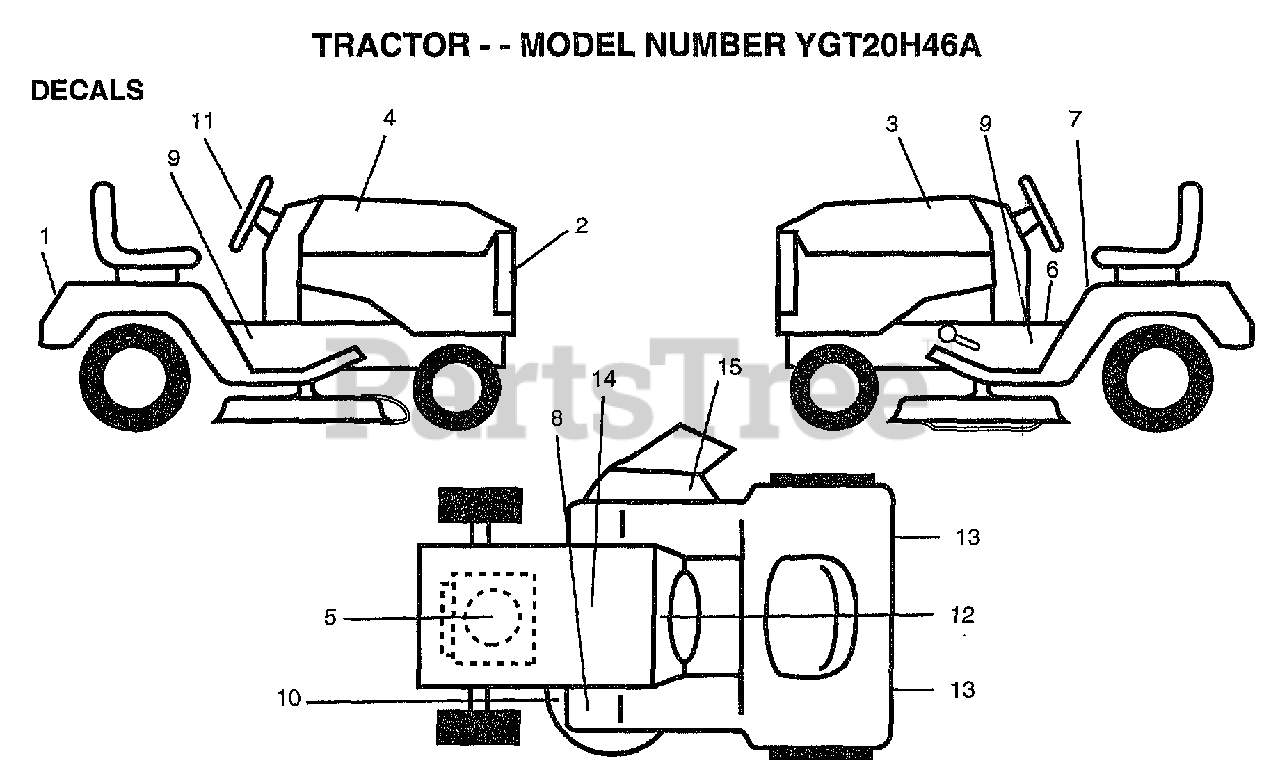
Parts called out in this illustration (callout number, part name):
1	DECAL FENDER
2	DECAL GRILLE
3	DECAL HOOD LH
4	DECAL HOOD RH
5	DECAL .B&S.20HP
6	DECAL BRAK PARK
7	DECAL.CAUT.ENG/FR
8	DECAL T
9	"DECAL-CHASSIS,46"""
11	DECAL INS STRG WH
12	DECAL OPER INSTR.
13	REFLECTOR-TAIL YT
14	DECAL.BATRY.3-3908
15	"DECAL, WARNING"
